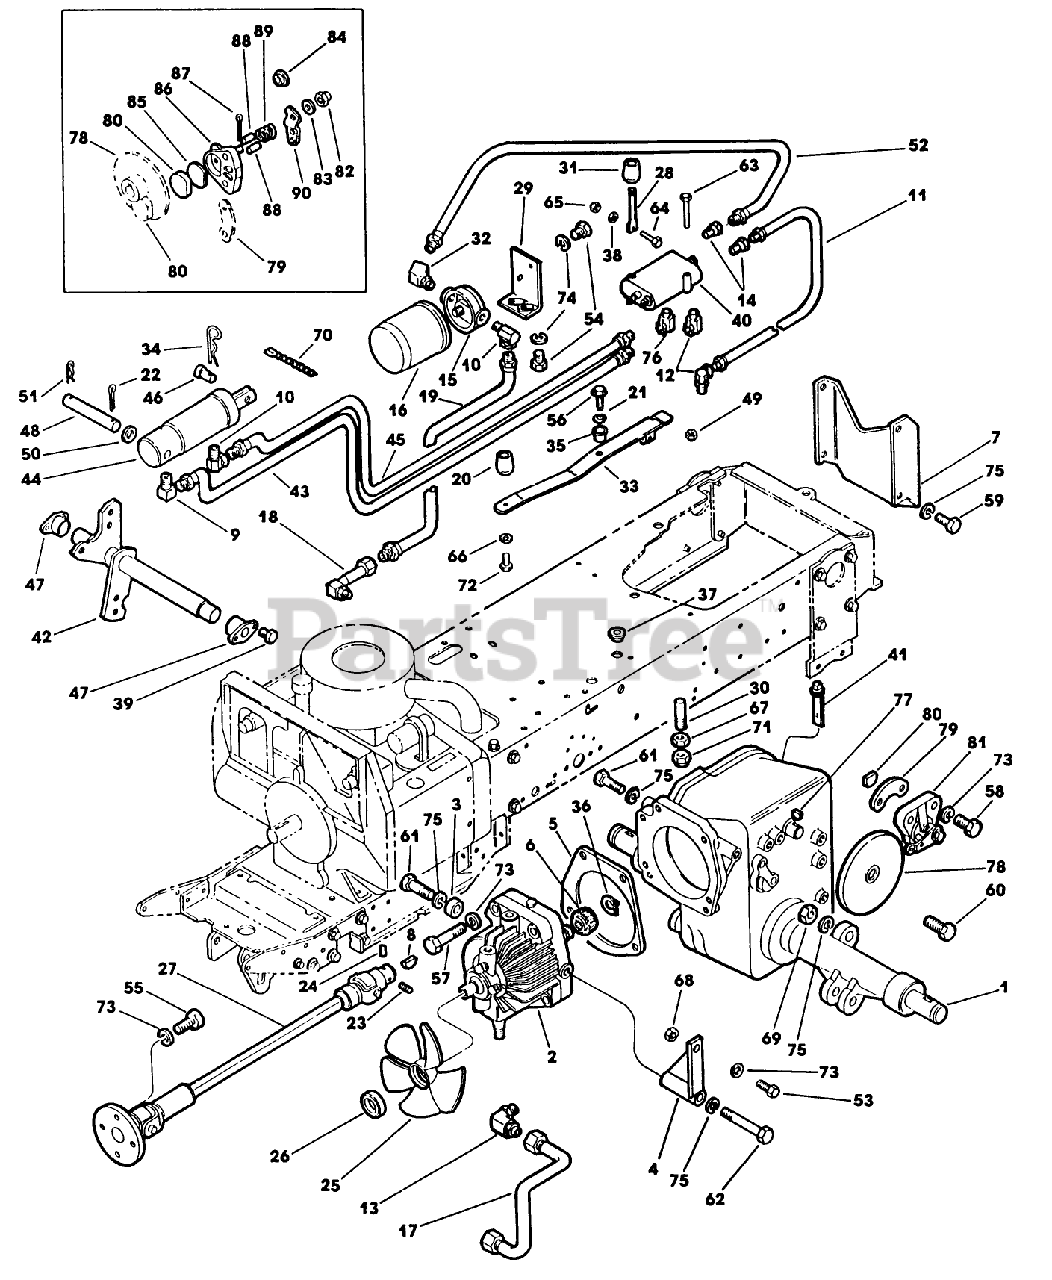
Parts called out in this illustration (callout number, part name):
5	GASKET
12	90 SWIVEL ELBOW
24	SET SCREW
25	FAN
27	SHAFT AY - DRIVE
34	PIN-HAIR
37	BUSHING
53	SCREW - HEX
56	SCREW-THD ROLL, HWH
62	SCREW-HH
65	NUT E
67	NUT
68	NUT
71	NUT-LOCK, CONE
73	WASHER
78	BRAKE AY-DISC T
80	PAD - BRAKE
